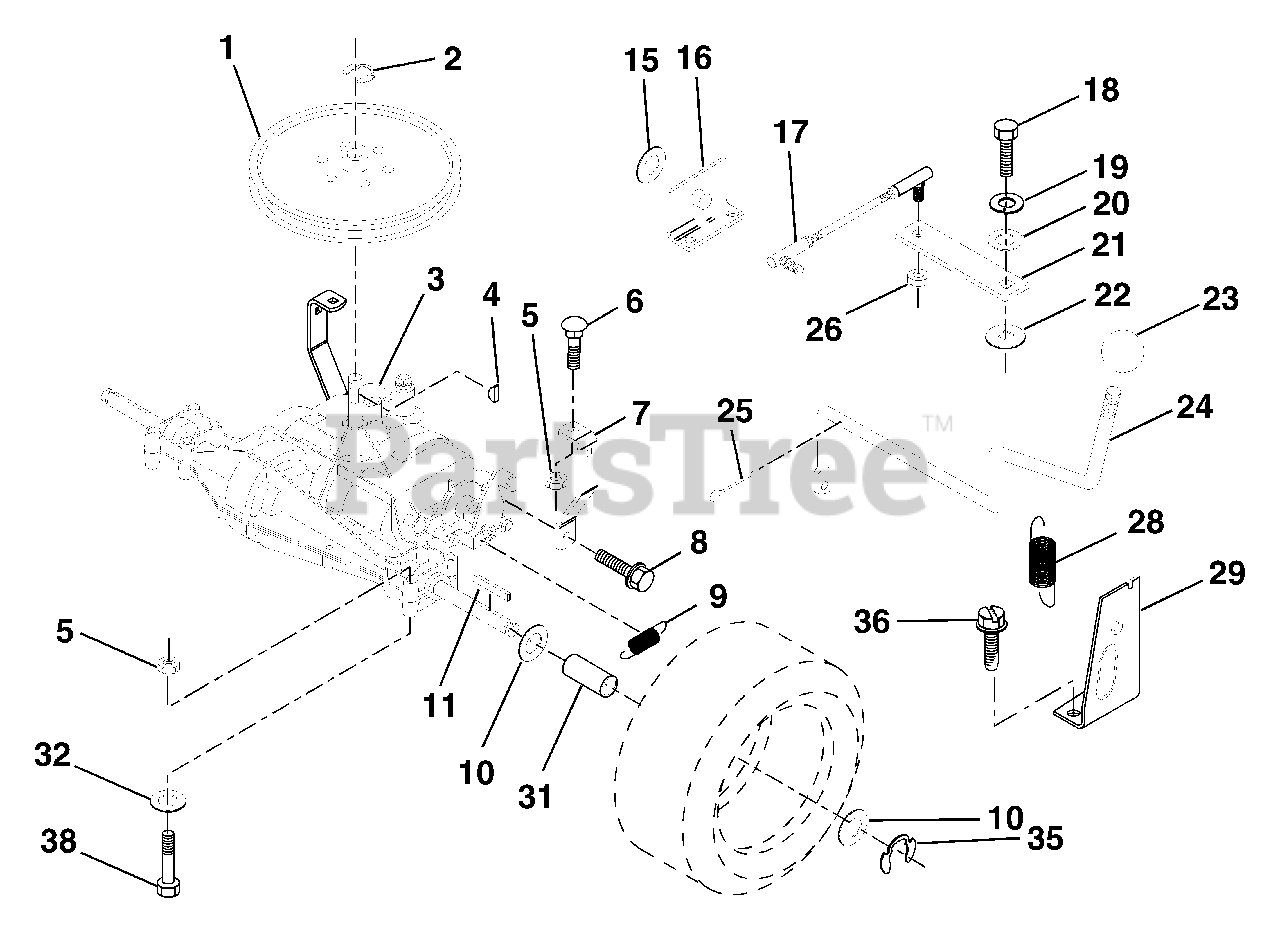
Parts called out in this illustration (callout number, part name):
2	Ring, Retainer
3	Transaxle - Peerless Model No. 930-009A
4	Key, Woodruff #9
5	Nut, Crownlock 5/16-18
6	Bolt, Carriage 5/16-18 UNC x 3/4
7	Strap, Torque
8	Screw 5/16-18 x 3/4
9	Spring, Brake
10	Washer 25/32 x 1-1/4 x 16 Ga.
11	Key, Square
15	Washer 17/32 x 1 x 16 Ga.
16	Support Handle Shift LH
17	Link, Shift
18	Bolt, Fin Hex 1/4-28 UNF x 3/4 Gr. 8
19	Washer, Lock 1/4
20	Washer 9/32 x 3/4 x 10 Ga.
21	Arm, Shift
22	Washer, Shift Plate
23	Knob, Rd 1/2-13
25	Pin, Cotter 1/8 x 1
26	Locknut 5/16-24 UNF
28	Extension, Spring
29	Support Handle Shift RH
31	Spacer Axle
32	Washer 11/32 x 11/16 x 16
36	Screw, Thd. Cut 1/4-20 x 1/2
38	Bolt, Hex Hd 5/16-18 x 2-3/4
